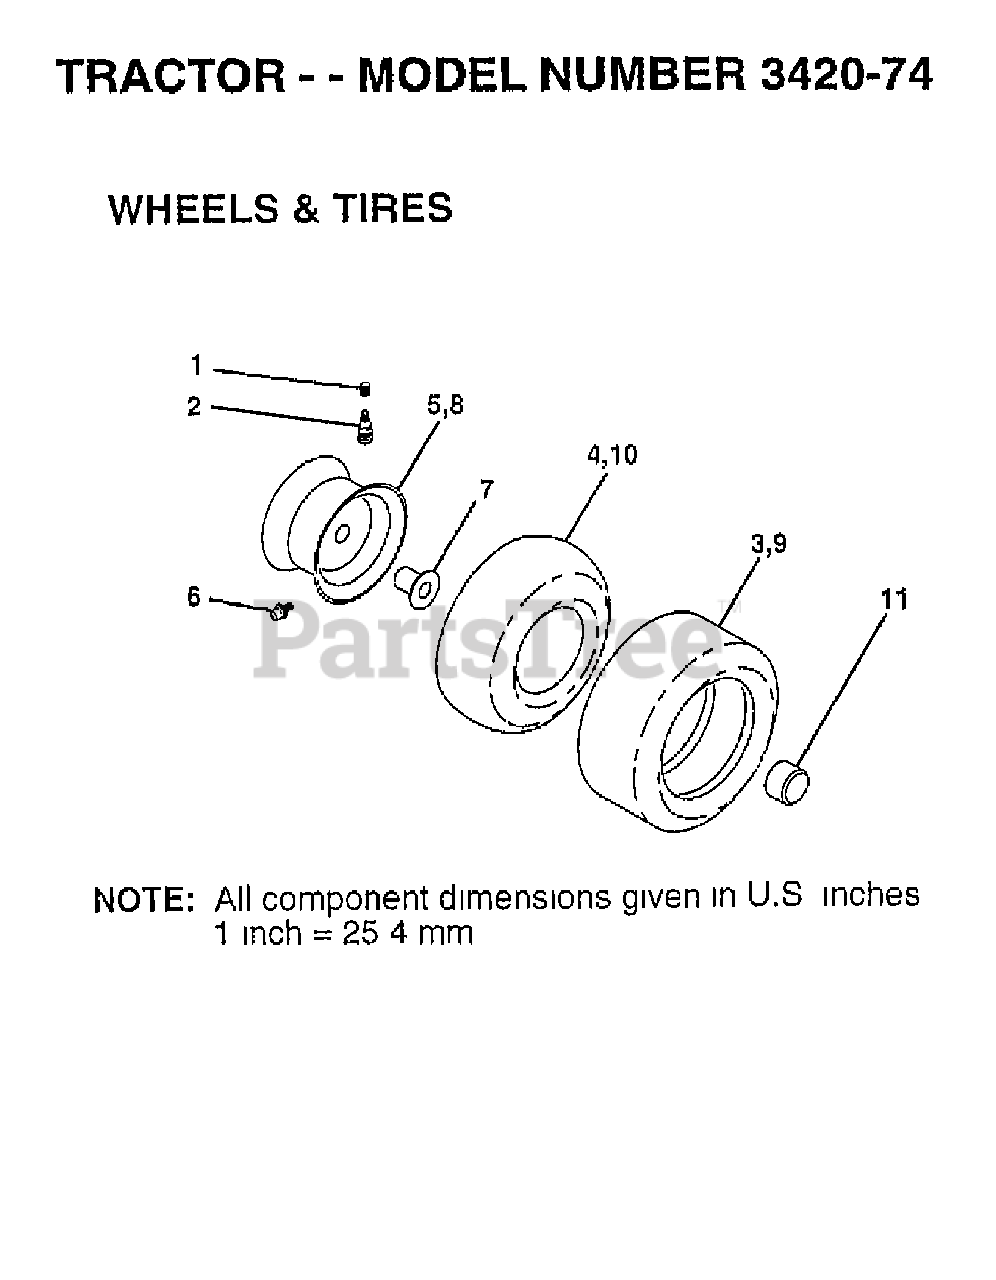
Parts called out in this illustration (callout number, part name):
1	VALVE CAP
2	VALVE STEM LT
3	TIRE HEAVY DUTY
4	TUBE.5.3/4.5/6
5	RIM.ASM.6".FRONT.SILVER
6	FITTING LT
7	BEARING T
8	RIM 8" SILVER
9	TIRE 20X8-8 TURF SAVER
10	TUBE - UNIVERSAL FOR 8" RIM
11	CAP.HUB.FRONT.LT.BLACK
